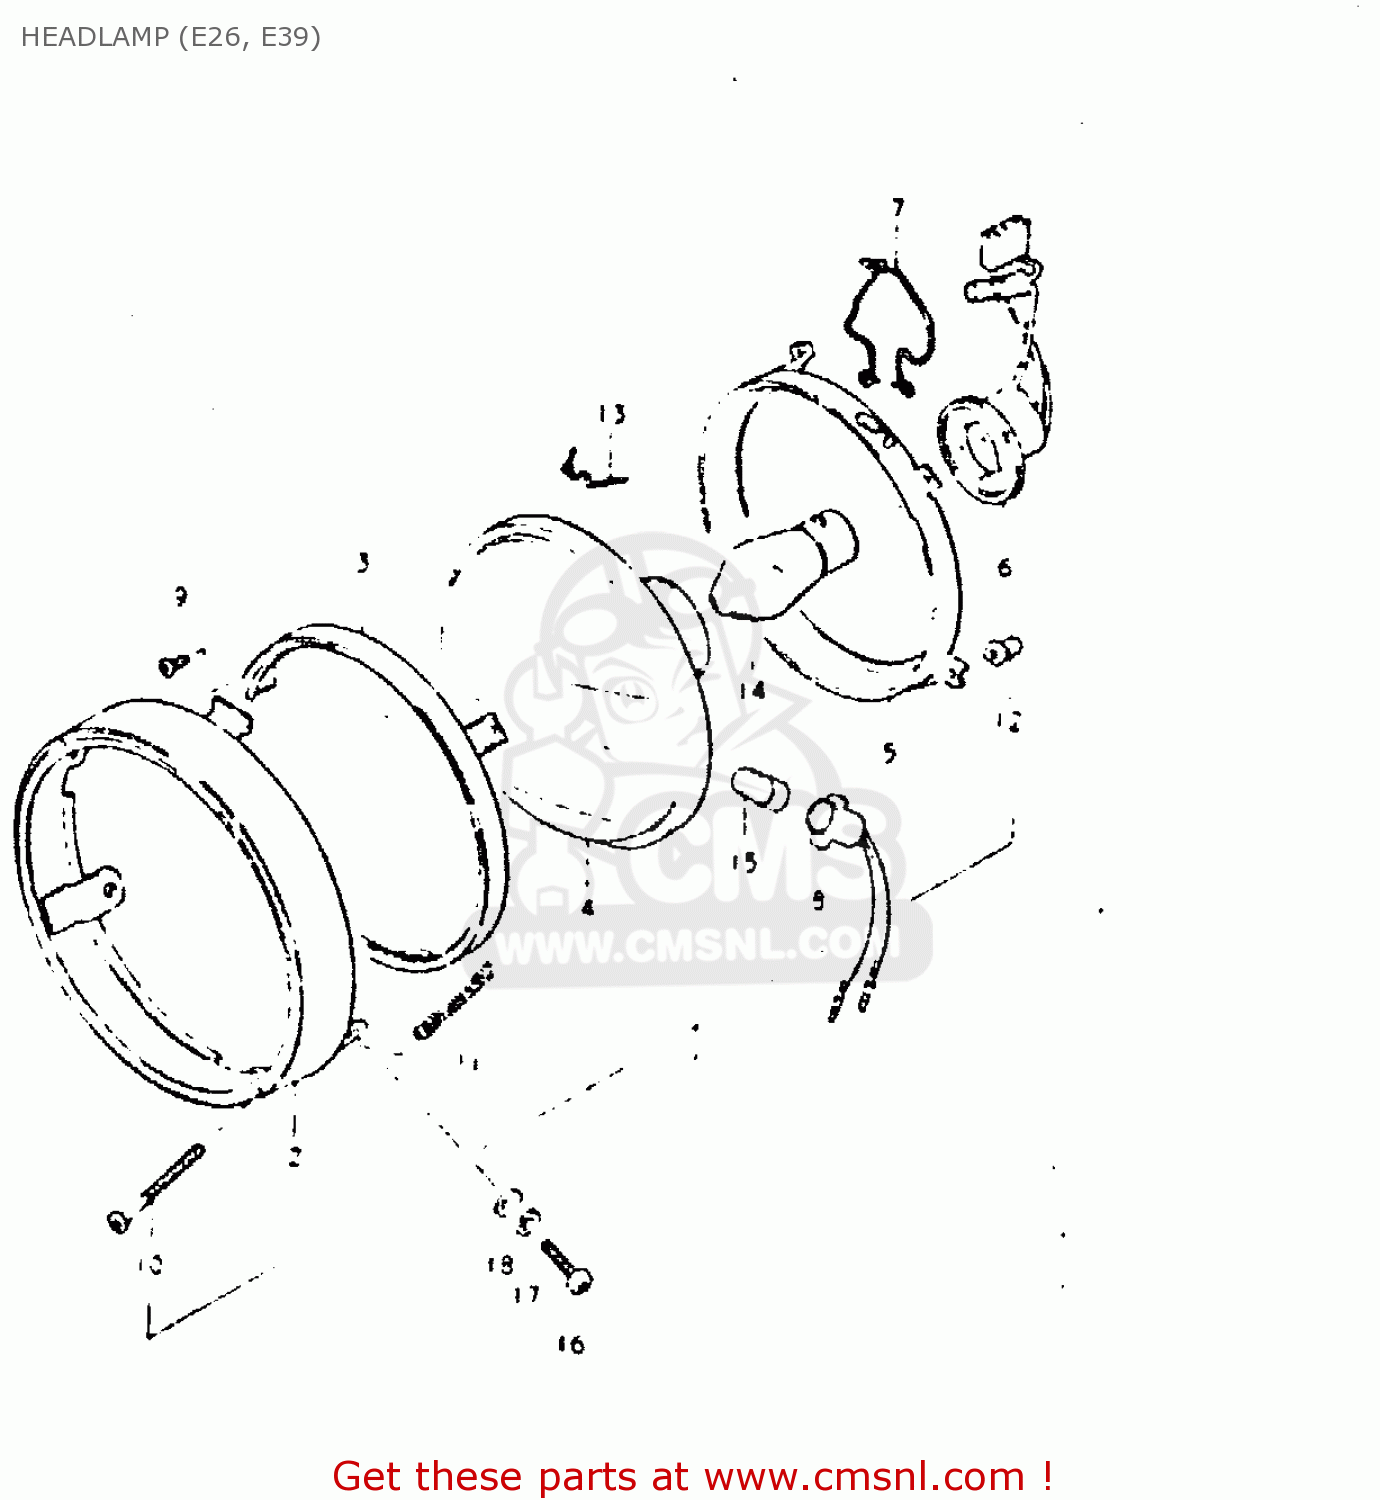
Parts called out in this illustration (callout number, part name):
1	HEADLAMP ASSY
2	RIM
3	RETAINER,HEADLAMP
4	UNIT
5	RING, MOUNTING
6	SOCKET
7	CLAMP,HEADLAMP
8	SOCKET
9	SCREW
10	SCREW,HEADLAMP ADJUST
11	SPRING,ADJUSTING
12	NUT,HEADLAMP ADJUSTER
13	SPRING,HEADLAMP UNIT
14	BULB (6V,25/25W)
15	BULB(6V4W,STANLEY,A1364J)
16	SCREW
17	LOCK WASHER
18	WASHER
